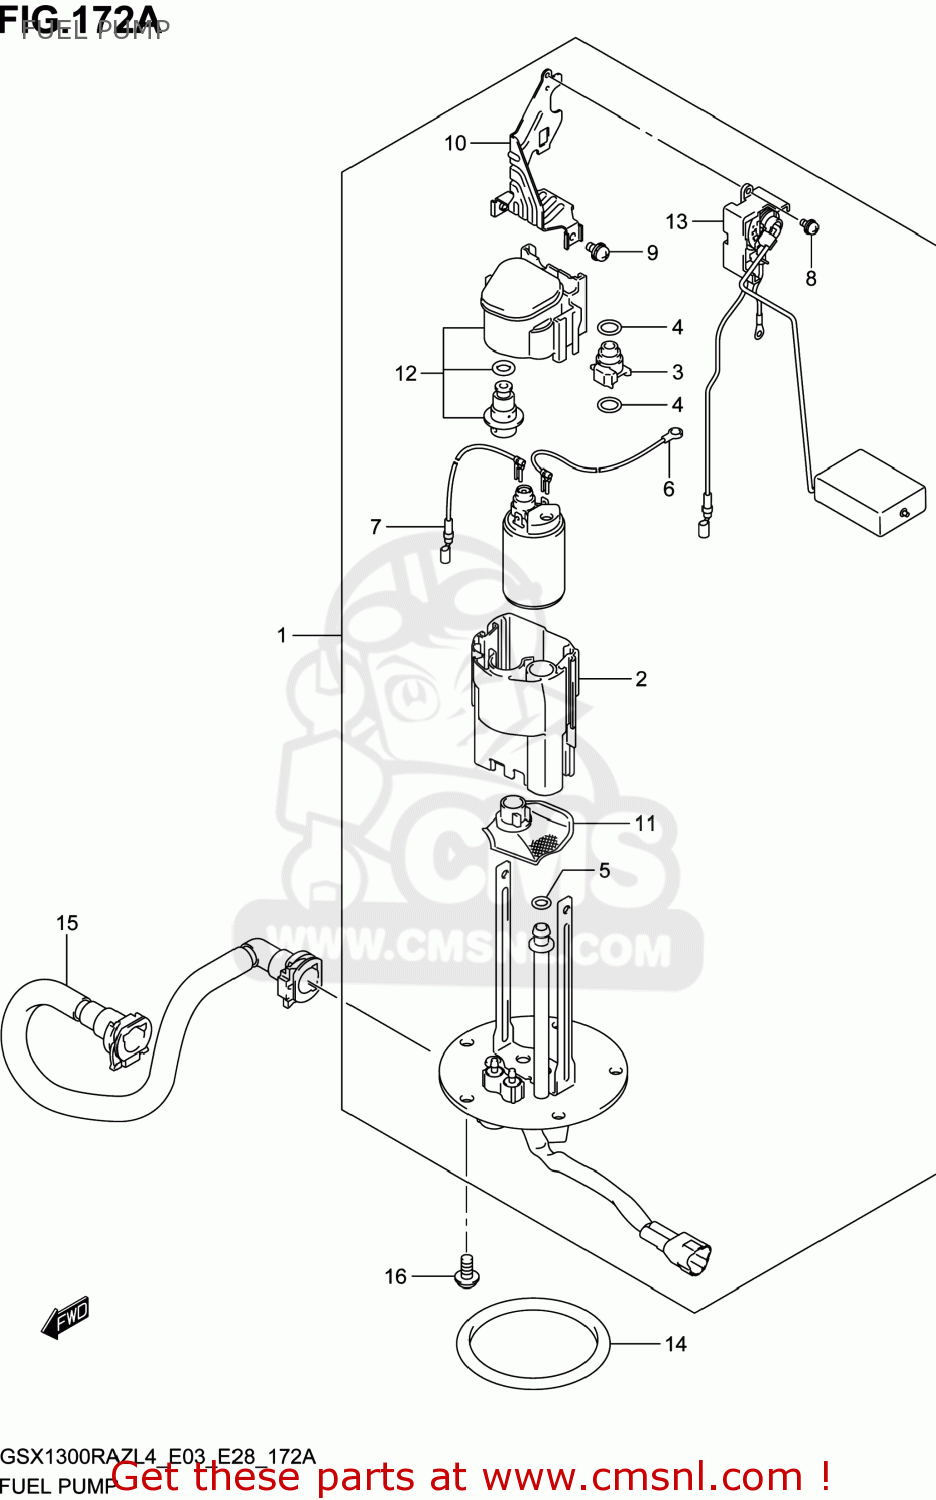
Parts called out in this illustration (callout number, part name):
1	PUMP ASSY,FUEL
2	CUP
3	JOINT
4	O RING
5	O RING
6	WIRE,EARTH
7	WIRE,LEAD
8	SCREW
9	SCREW
10	BRACKET,FUEL GAUGE
11	STRAINER
12	REGULATOR,FUEL
13	GAUGE ASSY,FUEL LEVEL
14	O RING,FUEL PUMP
15	HOSE,FUEL
16	BOLT
